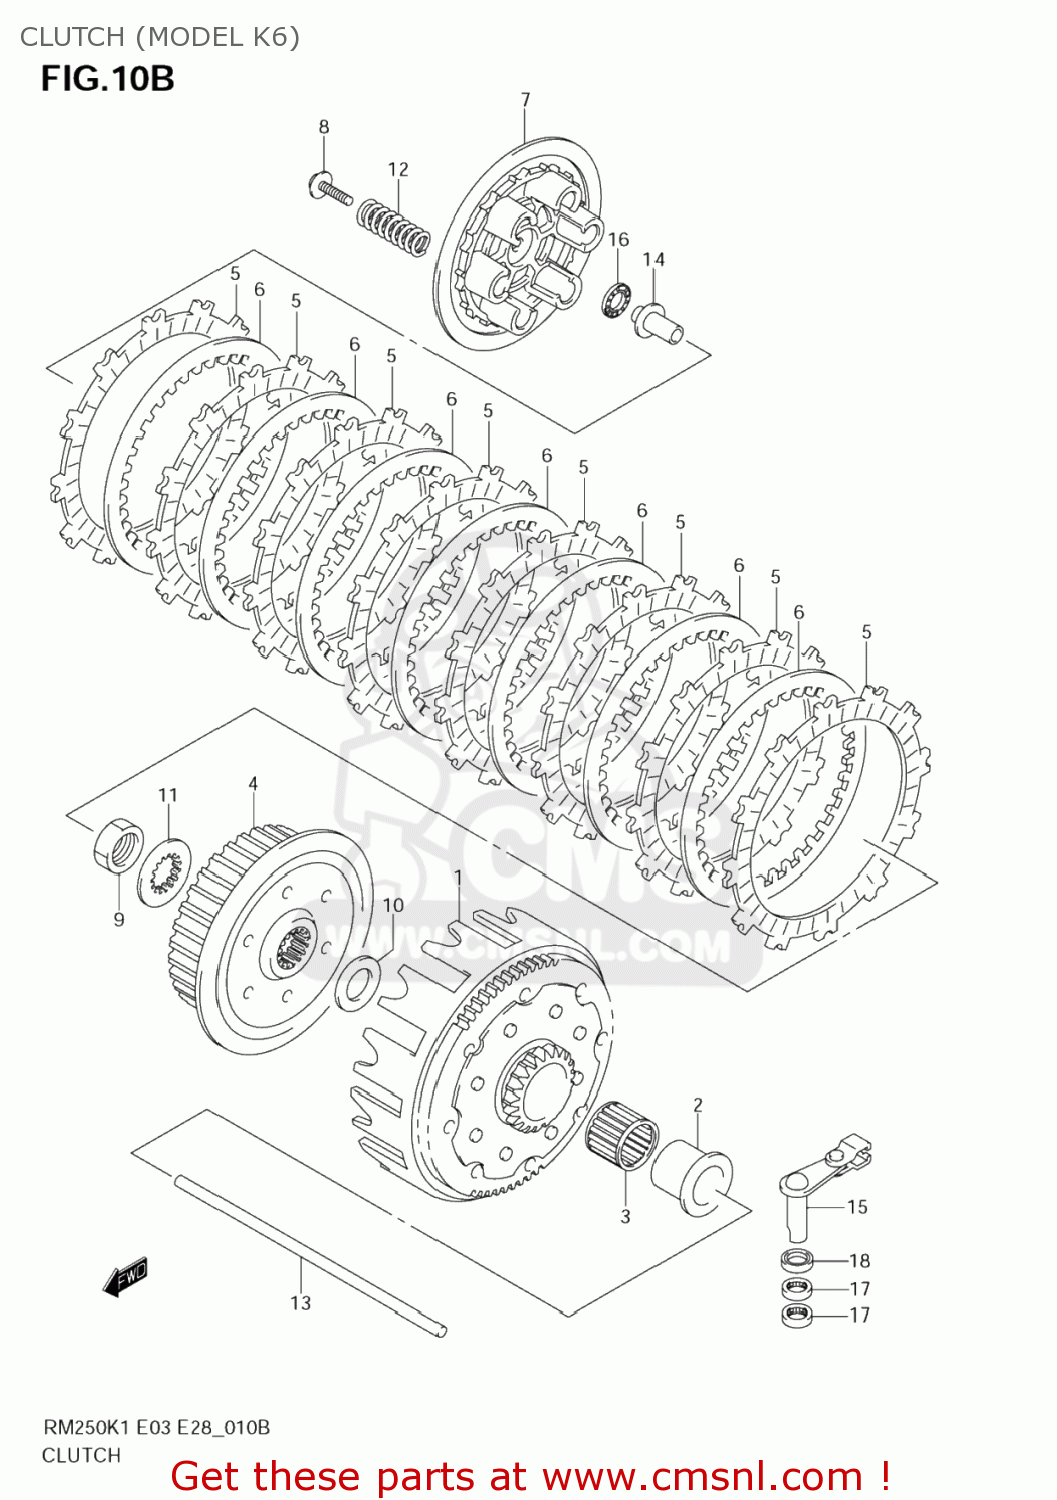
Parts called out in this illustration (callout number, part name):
1	GEAR ASSY,PRI DRIVEN
2	SPACER,PRIMARY DRIVEN GEAR
3	BEARING(29X34X27)
4	HUB,CLUTCH SLEEVE
5	PLATE,CLUTCH DRIVE (NAS)
6	PLATE,CLUTCH DRIVEN (NAS)
7	DISC,CLUTCH PRESSURE
8	BOLT(5X25)
9	NUT
10	WASHER(22.5X39X3)
11	WASHER,LOCK
12	SPRING
13	ROD,CLUTCH PUSH
14	PIECE,CLUTCH PUSH
15	CAMSHAFT,CLUTCH RELEASE
16	BEARING(10X22X2.8)
17	BEARING(12X16X10)
18	SEAL,OIL(12X19X5)
